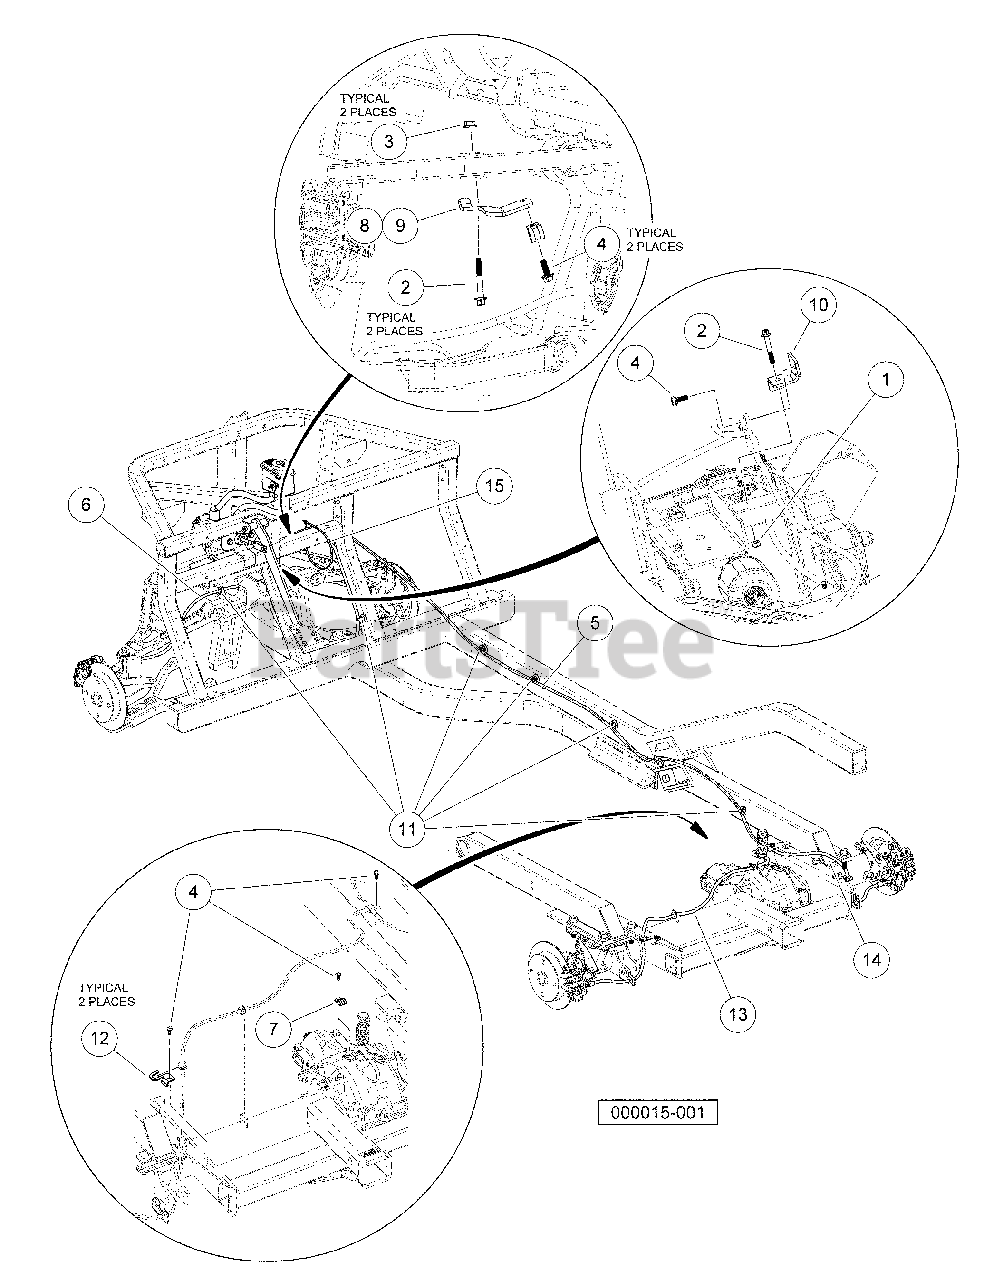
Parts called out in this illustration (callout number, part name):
1	Locknut, M6-1.00 Nylon Insert
2	Bolt, Flanged Head, M6x1.0x40
3	Nut-m6x1.0 Flng All Mtl Lock
4	Screw, M6 X 16 Tt Hx Fl Hd
5	Assembly, Brake Line, Rear
6	Assembly, Brakeline, Front
7	P-Clamp, Insulated .312 In
8	Bracket, Brake Line, Left
9	Bracket, Brake Line, Right
10	Bracket, Tee, Brakeline
11	Clip, Brake Line
12	Bracket, Line, Hydraulic
13	Brkt, Line, Hyd, Shk Mnt, Drv
14	Brkt, Line, Hyd, Shk Mnt, Pass
15	Tie Wrap, 11" Nylon
